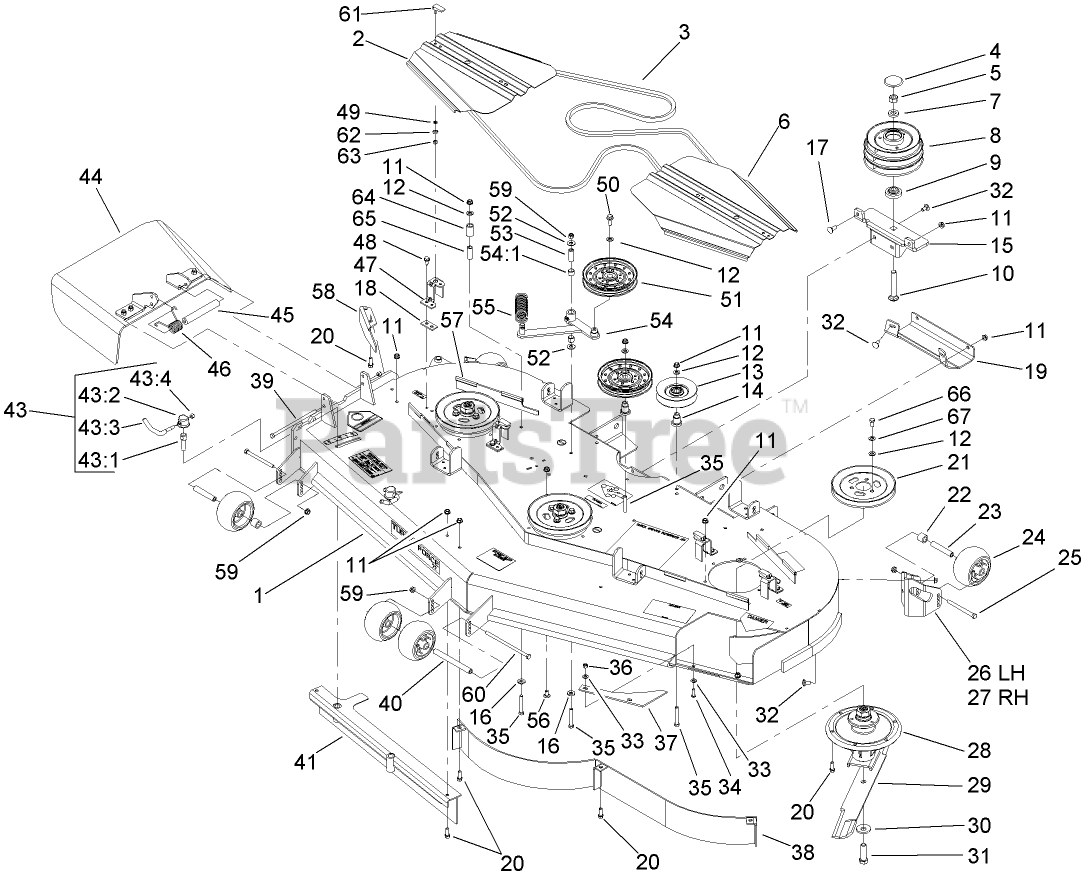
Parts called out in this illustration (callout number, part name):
1	DECK DECAL ASM
2	COVER-BELT, RH
3	BELT-V
4	CAP-PLASTIC
5	NUT-HEX
6	COVER-BELT, LH
7	SPACER
8	PULLEY AND BEARING ASM
9	SPACER-FLANGED
10	BOLT-CARRIAGE
11	NUT-HHF, WHIZ
12	WASHER-FLAT
13	PULLEY-IDLER
14	MOUNT-PULLEY
15	MOUNTING BRACKET ASM
16	WASHER-BELLEVILLE
17	BOLT-CARR
18	SPACER-COVER, BELT
19	Plate-Skid
20	SCREW-HWH
21	PULLEY
22	TUBE-SPACER
23	TUBE-SPANNER
24	ROLLER-SCALP, ANTI
25	SCREW-HH
26	MOUNT-WHEEL, LH
27	MOUNT-WHEEL, RH
28	SPINDLE ASM
29	BLADE-HI FLOW, 24.5 INCH
30	Washer-Blade Bolt, Heavy
31	SCREW-BLADE
32	SCREW-CARR
33	WASHER-SPRING
34	SCREW-HSBH
35	SCREW-HH
36	NUT-LOCK, NI
37	PLATE-TURBO
39	SCREW-HH
40	SPACER-WHEEL
43	LEVER ASM
43:1	Screw-Lock
43:2	CAP-LOCK
43:3	Lever-Lock
43:4	NUT-LOCK, NI
44	RUBBER DEFLECTOR ASM
45	SPACER
46	SPRING-TORSION
47	BRACKET-COVER
48	SCREW-HWHTF
49	WASHER
50	SCREW-HHF
51	Idler-Flat
52	WASHER-FLAT
53	BUSHING
54	IDLER ARM ASM
54:1	SLEEVE-BEARING
55	SPRING-EXTENSION
56	SCREW-CARR
57	STRIP-SEAL
58	BAFFLE-DISCHARGE
59	NUT-LOCK, NI
60	SCREW-HH
61	HANDLE-LATCH, SWELL
62	BUSHING-LATCH, SWELL
63	NUT-LOCK, HH
64	SPACER-RUBBER
65	SPACER-PIVOT, IDLER
66	SCREW-HH
67	WASHER-BELLEVILLE
